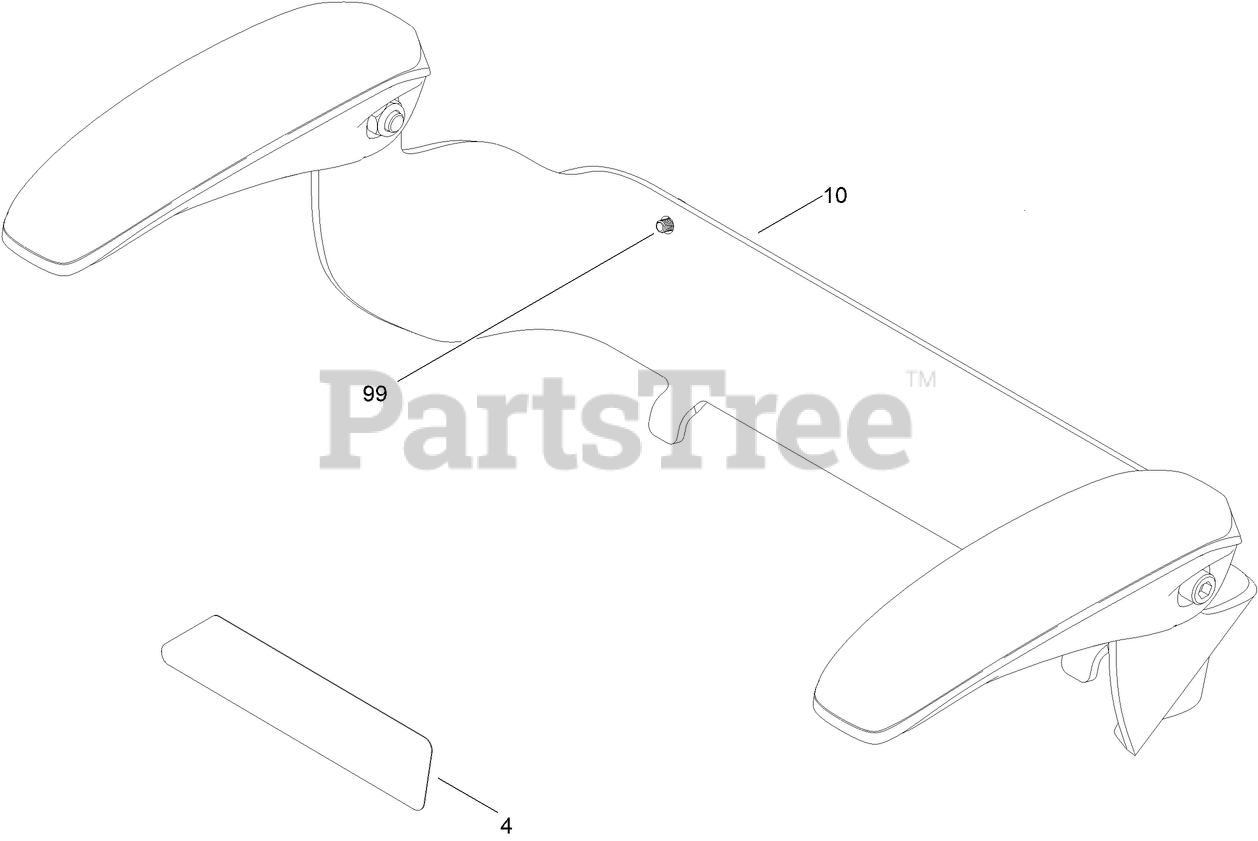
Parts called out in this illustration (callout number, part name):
4	DECAL ZXM6075
10	KIT-ARM REST
99	SCREW-HH
